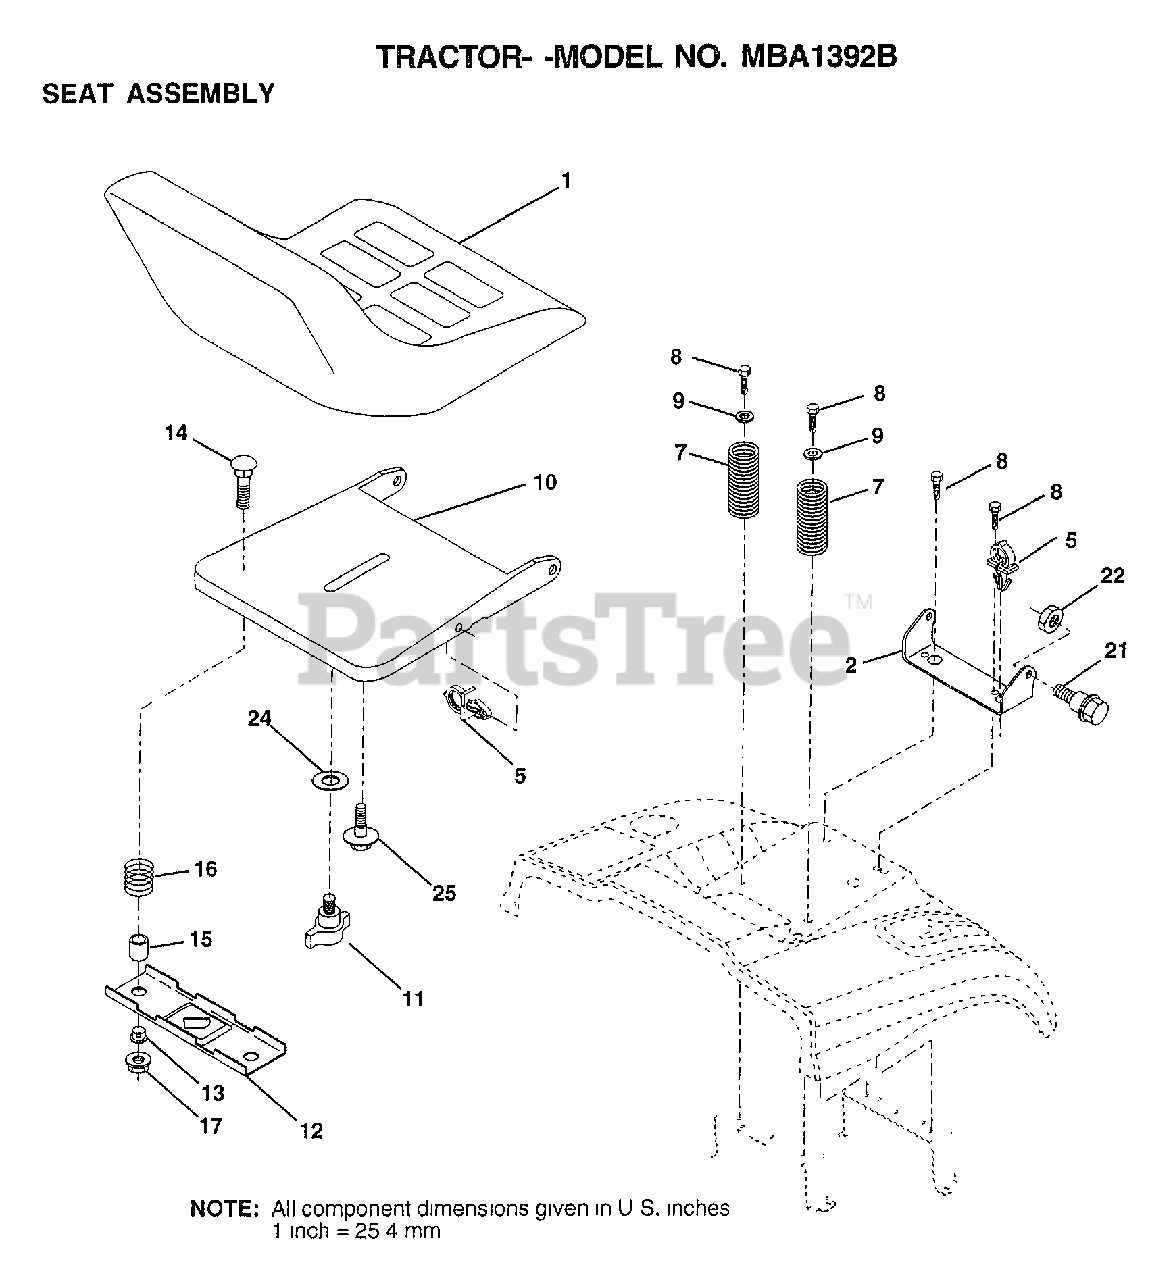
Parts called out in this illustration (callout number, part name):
1	SEAT.2400/1416.BK
2	BRACKET PVT SEAT
5	CLIP.PUSH-IN.HING
7	SPRING COMPRESSIO
8	SCREW
9	WASHER
10	PAN-SEAT
11	KNOB.SEAT.ADJ.WINGNUT
12	BRKT SWITCH
13	BUSHING
14	BOLT-RD HD SQ NK
15	SPLIT SPACER
16	SPRING
21	BOLT
22	NUT
24	WASHER
25	"BOLT,SHOULDER"
